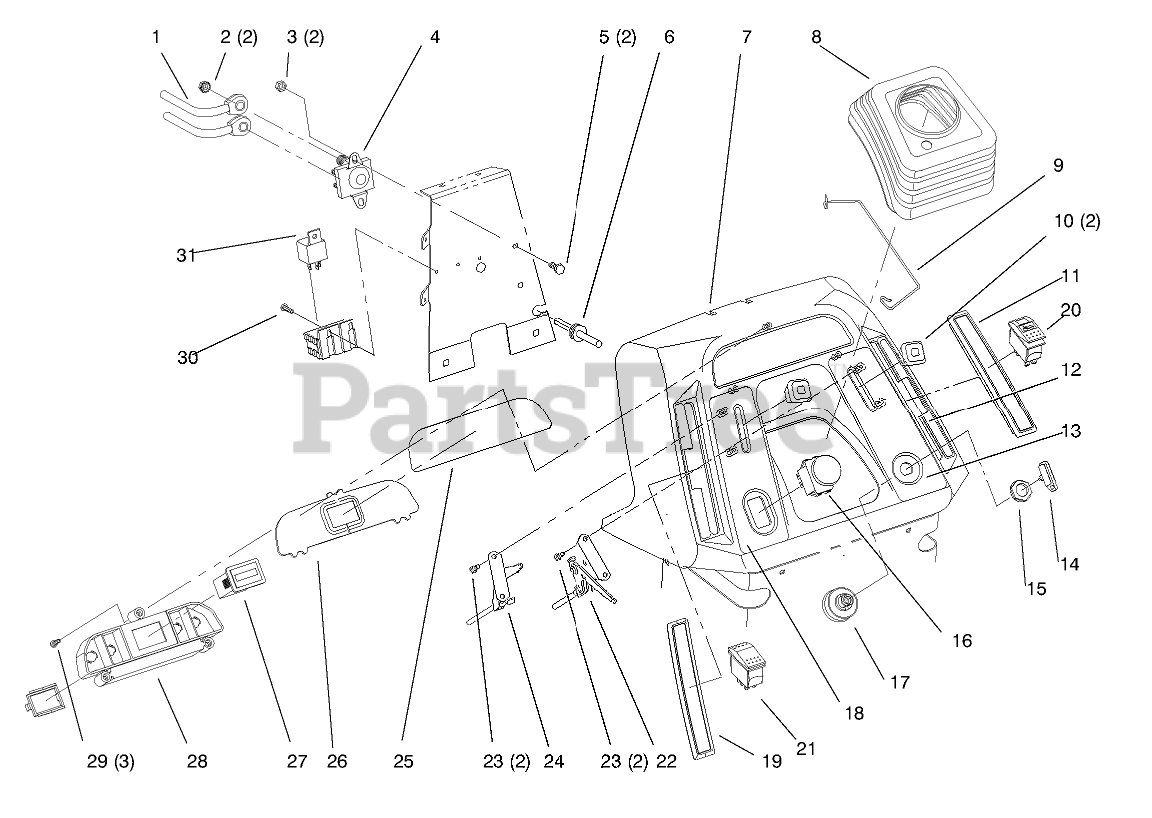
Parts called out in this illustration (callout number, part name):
8	BOOT-STEERING
9	CLIP-BOOT
11	Cover-Cruise (Only On: 72085)
11	Cover-Cruise (Only On: 72104)
13	Decal-Throttle/Ignition (Only On: 72085)
13	Decal-Dash (Only On: 72104)
14	KEY-IGNITION
16	SWITCH-PTO
17	SWITCH-IGNITION
18	Decal-Choke/PTO (Only On: 72085)
18	Decal-Dash (Only On: 72104)
19	COVER-SLOT, LH
20	SWITCH-CRUISE
22	CONTROL-THROTTLE (TWIN)
24	CONTROL-CHOKE (TWIN)
25	DECAL - DASH LENS
26	LENS-DASH
27	HOURMETER
28	4 LIGHT HOUSING
29	SCREW
30	SCREW-PPHTF
31	RELAY
